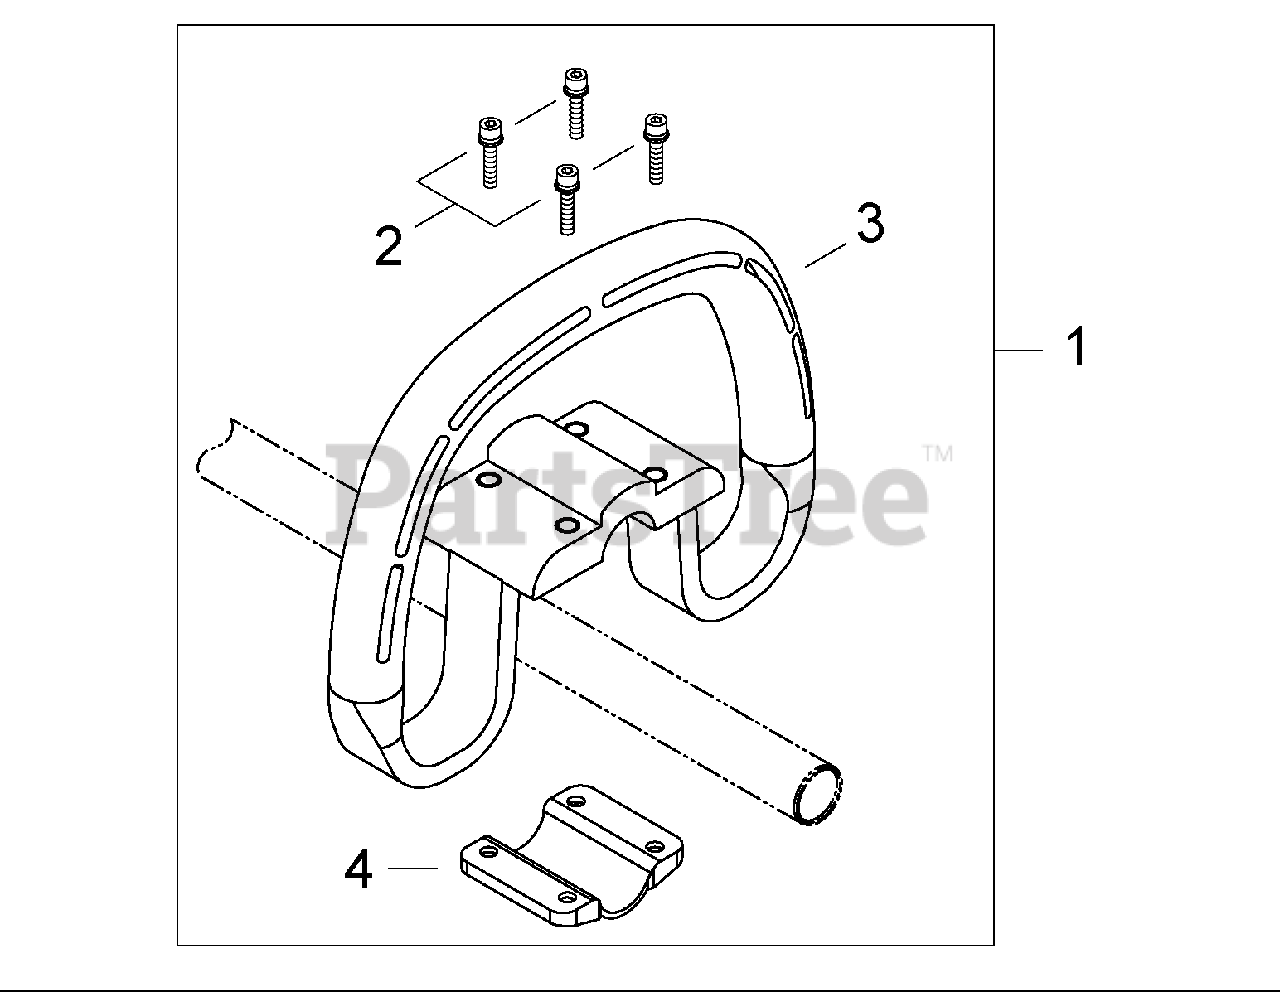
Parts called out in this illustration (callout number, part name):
1	HANDLE ASSY
2	SCREW - 5X25
3	HANDLE
4	CLAMP - LOWER
